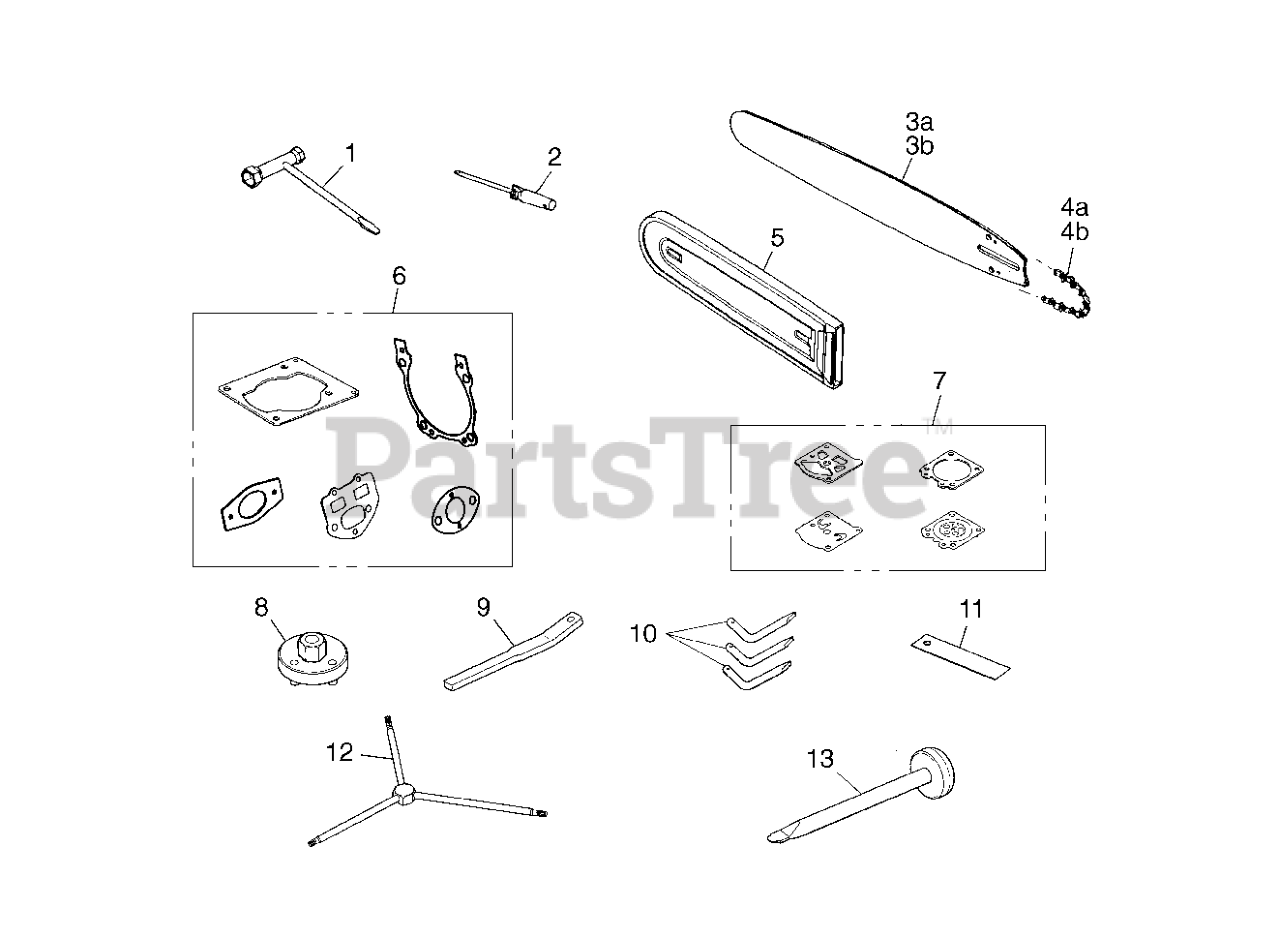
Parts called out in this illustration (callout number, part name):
3	16" BAR(FITS:GZ4500)
3	18" BAR(FITS: GZ4500)
4	16" CHAIN
4	18" CHAIN
